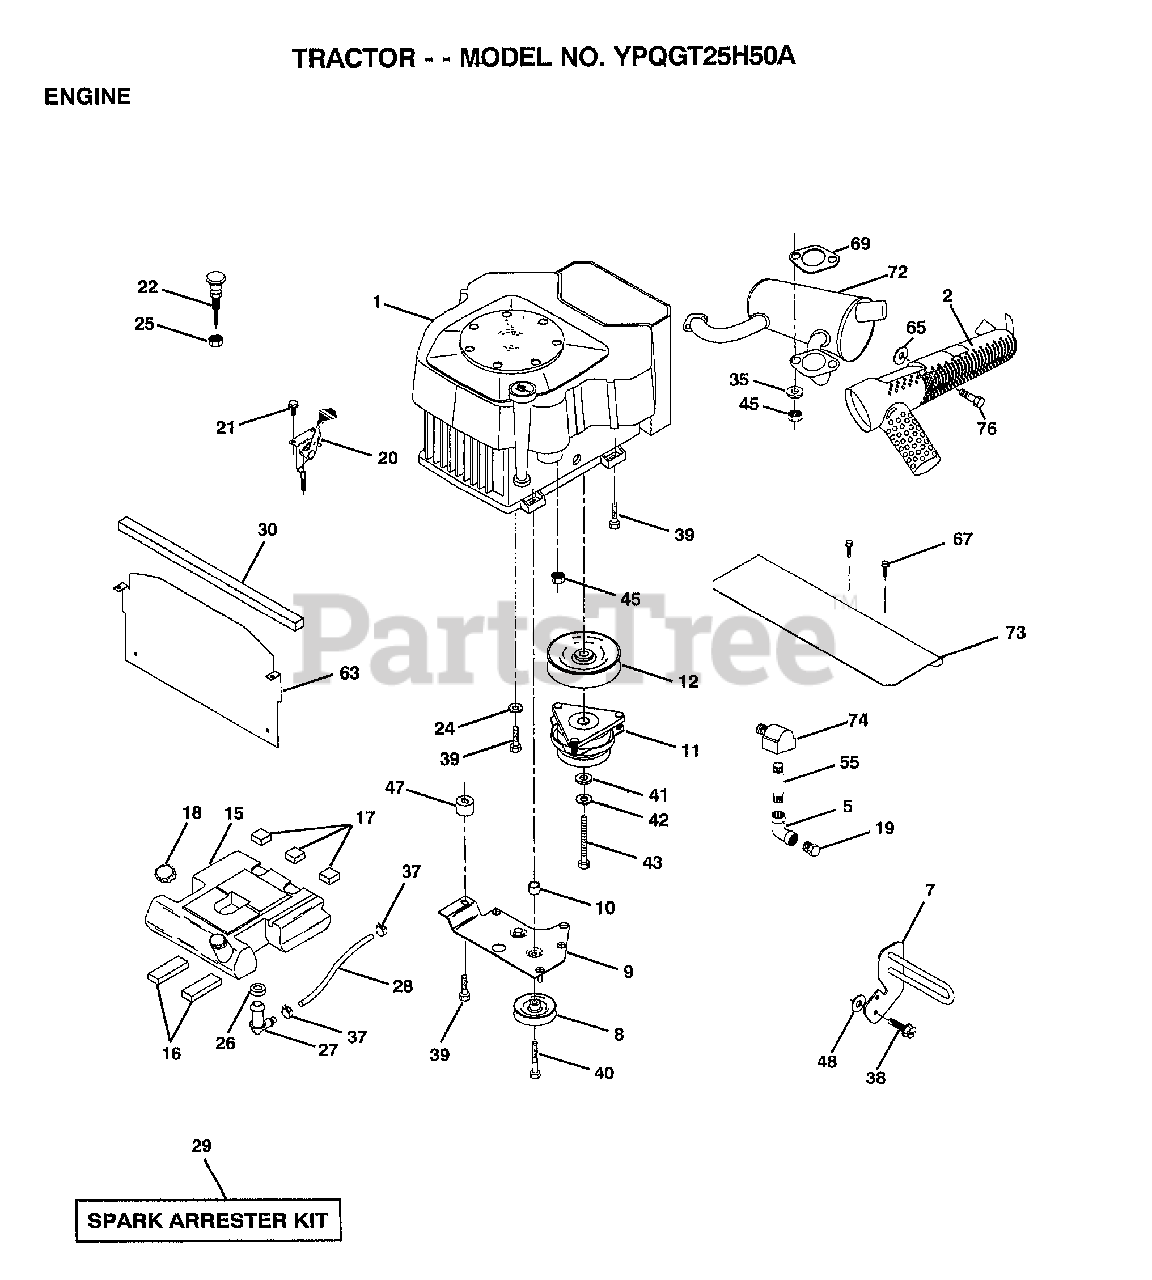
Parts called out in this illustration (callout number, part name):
2	MUFFLER VGT
5	ELBOW
7	GUARD.MUFFLER.ASM
9	KEEPER ASM BELT
10	BUSHING.
12	PULLEY.ENG.CLUTCH
15	TANK FUEL REAR
16	PAD IDLER TI
17	PAD-SPACER LT
18	CAP ASM FUEL
19	PLUG T
20	CONTROL THTL 37
21	SCREW LT
22	CONTROL.CHOKE.37
24	LOCKWASHER
25	"NUT,KEPS 3/8-24IM"
26	BUSHING OUTLET T
27	STEM.TANK.FUEL
29	SPARK ARREST KIT
30	EXTRUSION HOOD
35	WASHER.SPLIT
37	HOSE CLAMP
38	SCREW
39	SCREW.3/8-16X2.25
40	SCREW.TT.3/8-16X4
41	WASHER
42	LOCKWASHER
45	NUT FLANGE M8-125
47	SPACER.ENGINE
48	WASHER T
55	PIPE NIPPLE LT
63	HEAT.SHIELD.VGT.
64	SCREW
65	WASHER
67	SCREW
69	GASKET
72	"MUFFLER,PRE CV25"
73	SHIELD.MUF.KOHLER
74	ELBOW STREET BASS
76	SCREW
